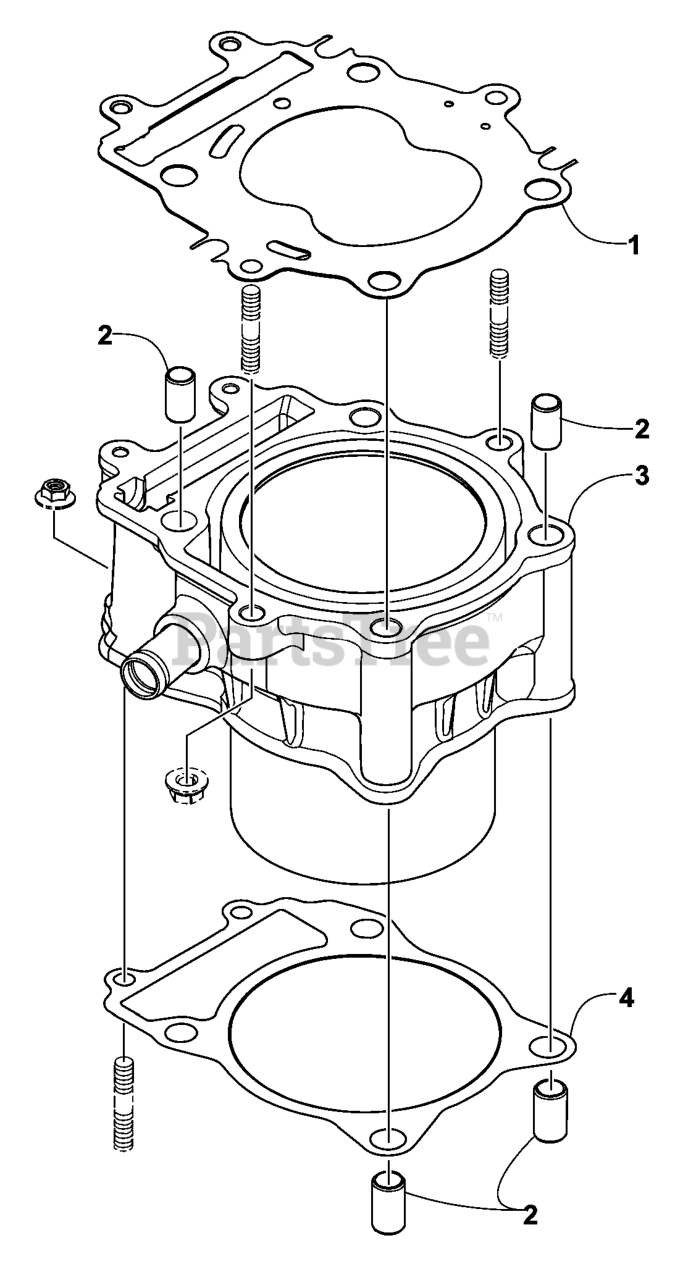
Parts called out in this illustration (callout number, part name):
1	GASKET-HEAD, CYLINDER
2	PIN-DOWEL
3	CYLINDER
4	GASKET-CYLINDER
